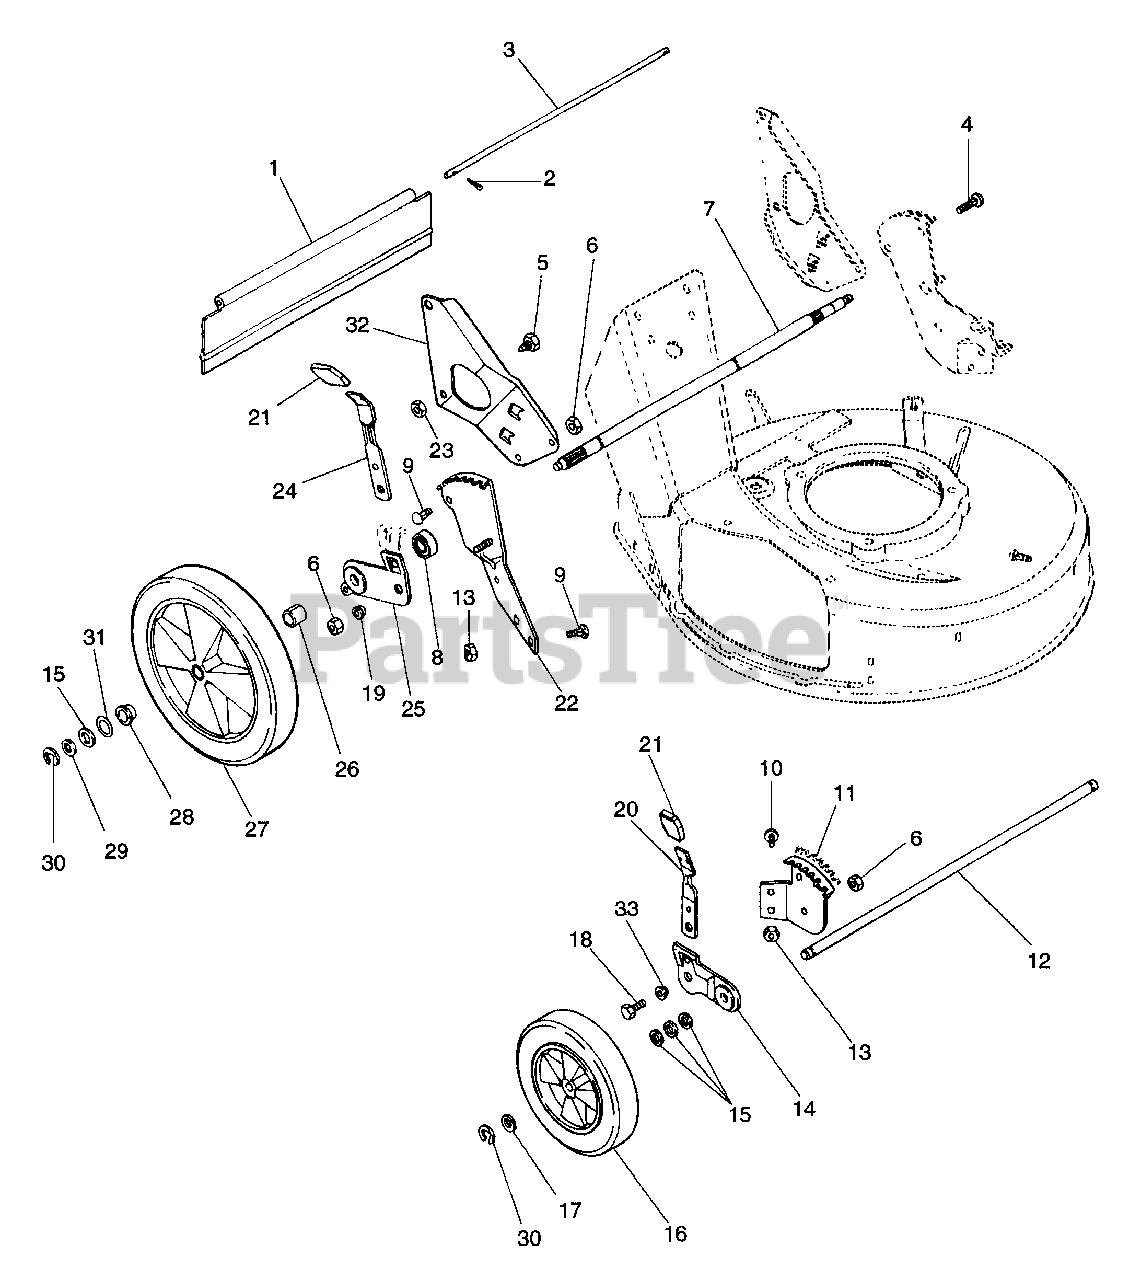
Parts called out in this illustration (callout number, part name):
1	REAR PROTECTIVE GUARD, PUSH
1	REAR PROTECTIVE GUARD, S.P.
2	PIN-COTR .06X.50
3	ROD
4	BLT-RDHDSQNK .31-18X1.0 SHT PL
4	BLT-RDHDSQNK .31-18X1.25 SHTPL
5	HANDLEBAR STUD
5	BLT-HEX .31-18X.75 PL GR5
6	NUT-LK .312-18 GR A PL
7	REAR AXLE,5/8 DIA
7	REAR AXLE-PUSH MOWER
8	BRG-BALL .625X1.383X.50
9	BLT-RDHDSQNK .312-18X.62SHTPL
10	BLT-RDHDSQSHNK .31-18X.50 YZ
11	FRONT QUADRANT, L.H.
11	FRONT QUADRANT, R.H.
12	FRONT AXLE
13	NUT-FLG. .312-18 PL
14	LEFT ADJUSTOR BRACKET ASSEMBLY
14	RIGHT ADJUSTOR BRACKET ASSEMBL
15	WSHR-FL-STL .520X.827X.062 YZ
16	WHEEL
17	WSHR-FL-STL .505X.880X.072 PL
18	BLT-HEX .31-18X.88 PL GR2
19	BSHG-FLG .32X.500X.344X.880
20	FRONT HEIGHT ADJUSTMENT LEVER
22	QUADRANT, REAR - L.H.
22	REAR QUADRANT, R.H.
23	NUT-LK-JAM-CTR .375-16 PL
24	HEIGHT ADJUSTMENT LEVER
25	REAR BRACKET & BEARING ASSEMBL
25	REAR BRACKET & BEARING ASSY RH
25	R.H. REAR ADJUSTOR BRACKET
25	REAR BRACKET&BEARING ASSY COMM
25	REAR ADJUSTMENT BRACKET L.H.
25	L.H. REAR ADJUSTOR BRACKET
26	SPACER TUBE,PUSH LH
26	SPACER TUBE PUSH RH
26	SPACER TUBE, SELF PROPEL
27	WHEEL
27	LH WHEEL
27	RH WHEEL
27	10 1/2 TIRE SKIN
28	BSHG-SLV .625X.750X.500
29	WSHR-FL-STL .630X1.005X.062 PL
30	RG-RTNG-EXT .500X.042 (E)
31	SEAL .625X.875X.125
32	RH HANDLEBAR MTG. BRKT.
32	LH HANDLEBAR MTG. BRKT.
33	BSHG-FLG .32X.500X.344X.880
